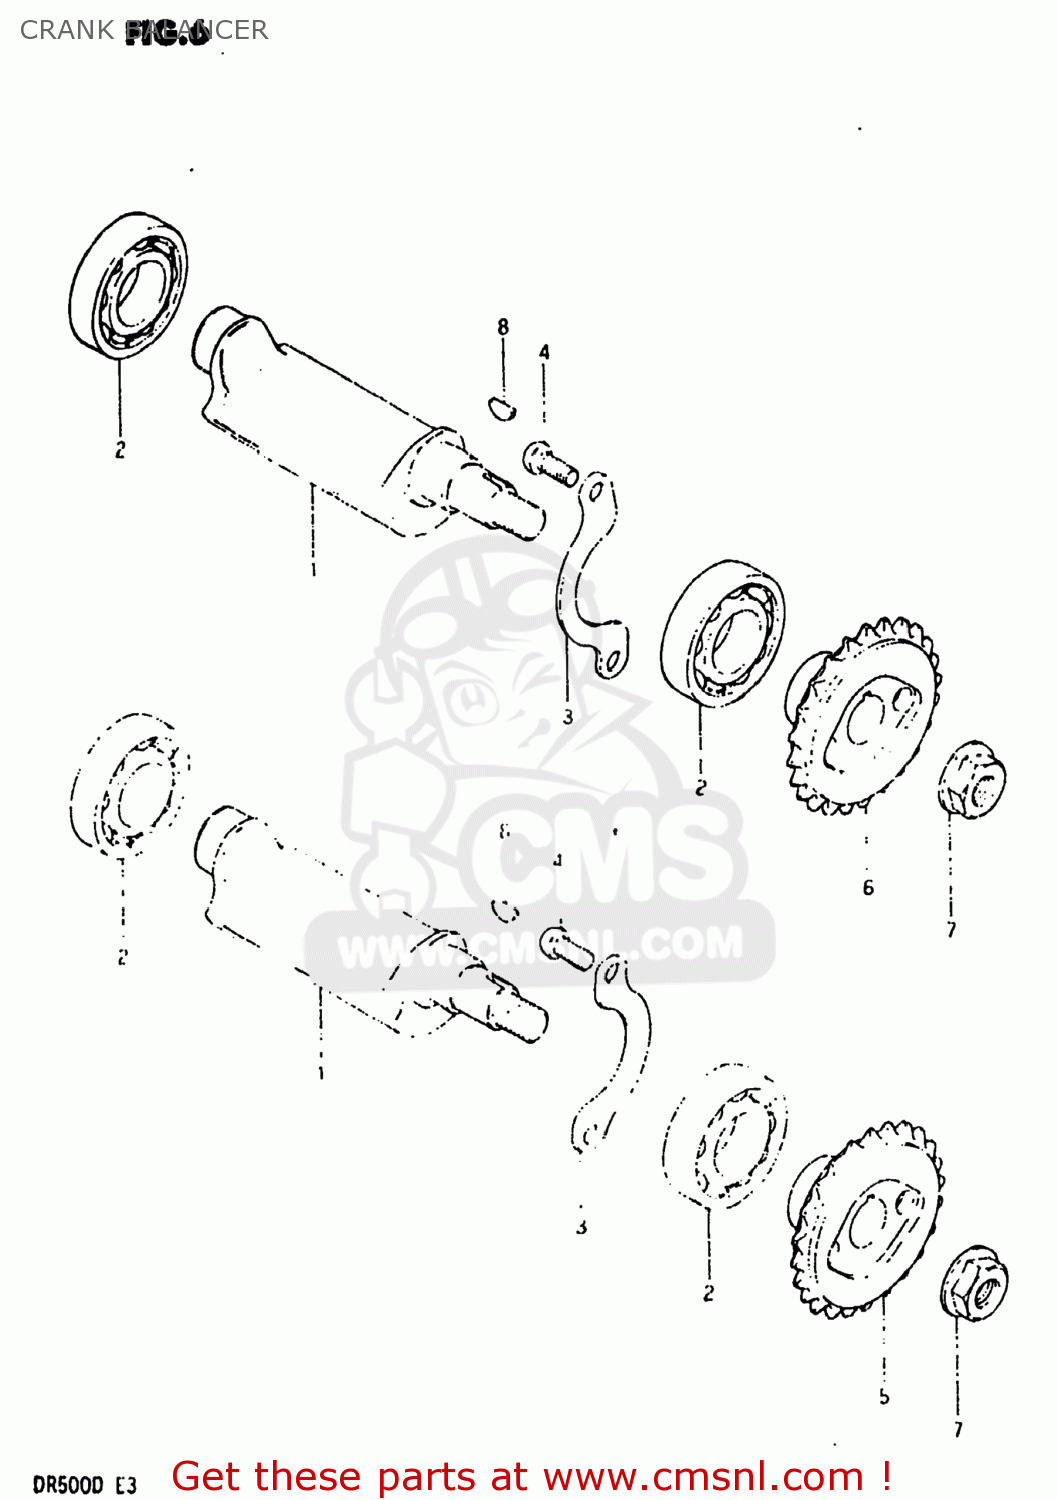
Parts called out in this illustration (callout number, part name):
1	BALANCER,CRANKSHAFT
2	BEARING
3	RETAINER,CRANK BAL BEARING
4	SCREW 6X12
5	SPROCKET,BALANCER DRIVE
6	SPROCKET,BALANCER DRIVE
7	NUT
8	KEY
